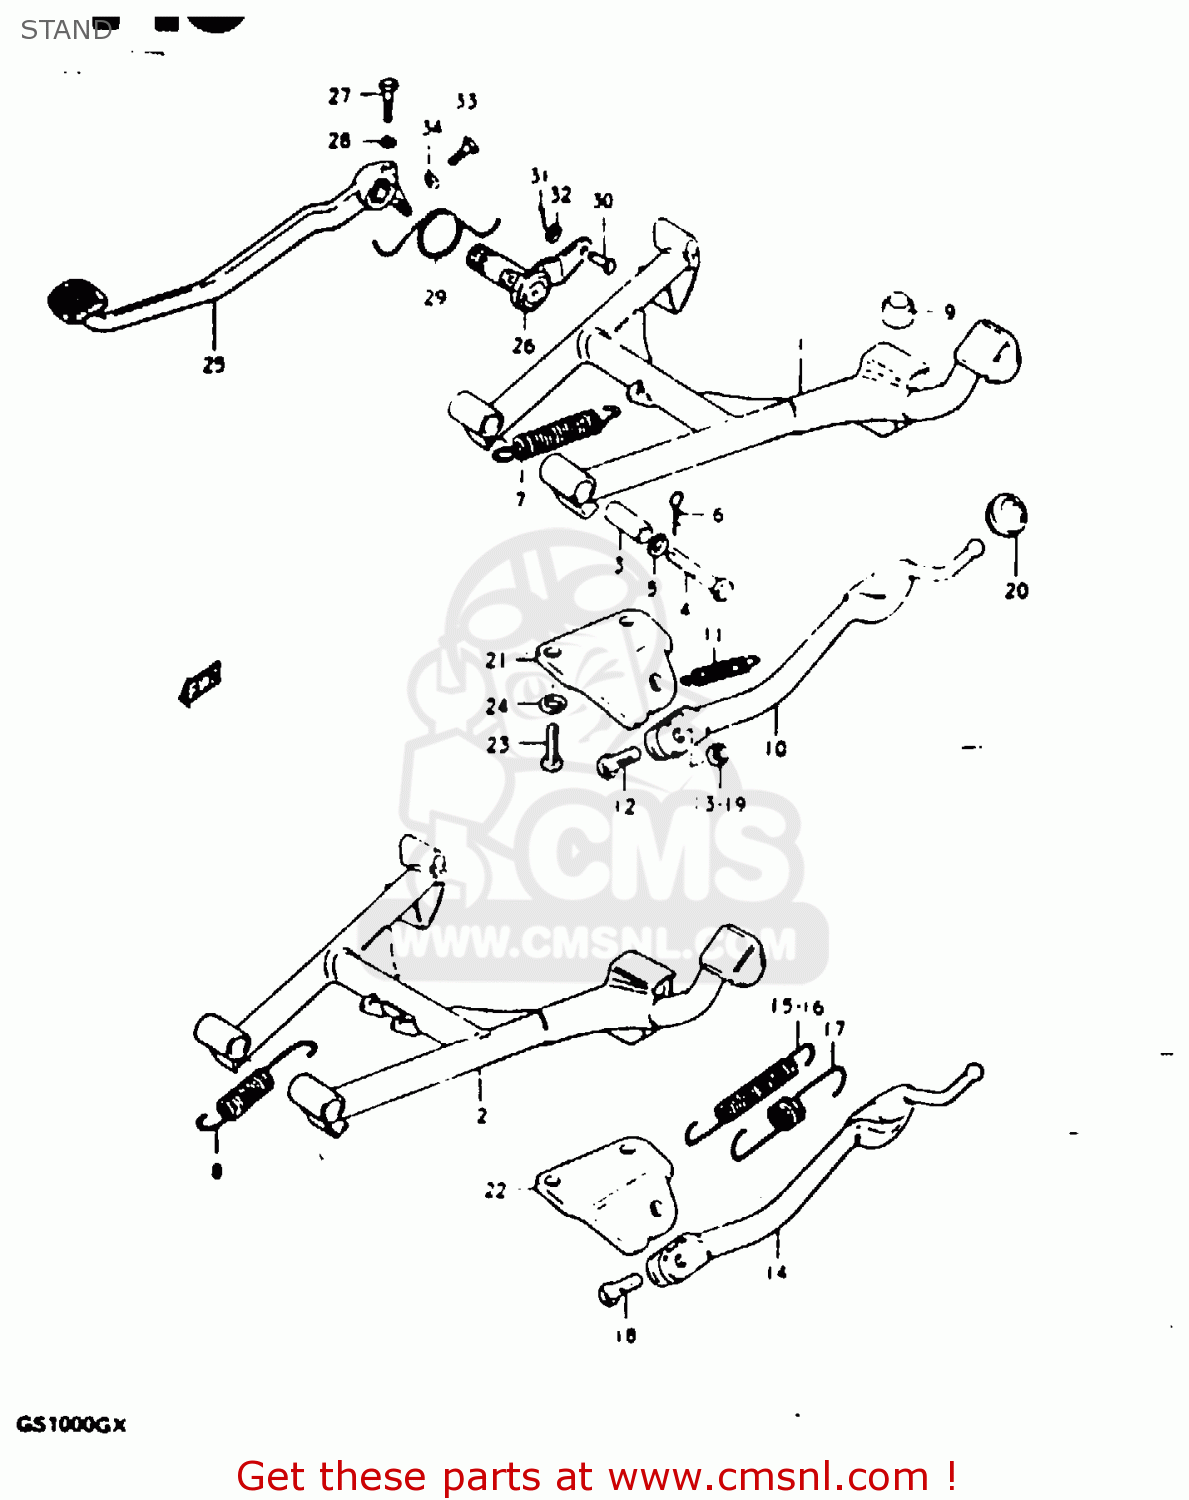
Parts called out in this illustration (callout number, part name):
1	STAND,CENTER
3	SPACER(10X16X38.8)
4	BOLT
5	LOCK WASHER
6	CLIP
7	SPRING
9	CUSHION
10	STAND,PROP
11	SPRING
12	BOLT(10X30)
13	NUT
20	CUSHION
21	BRACKET,SIDE STAND
23	BOLT
24	LOCK WASHER
25	PEDAL,BRAKE
26	ARM,BRAKE PEDAL
27	BOLT
28	LOCK WASHER
29	SPRING
30	PIN
31	PIN
32	WASHER
33	BOLT
34	NUT
